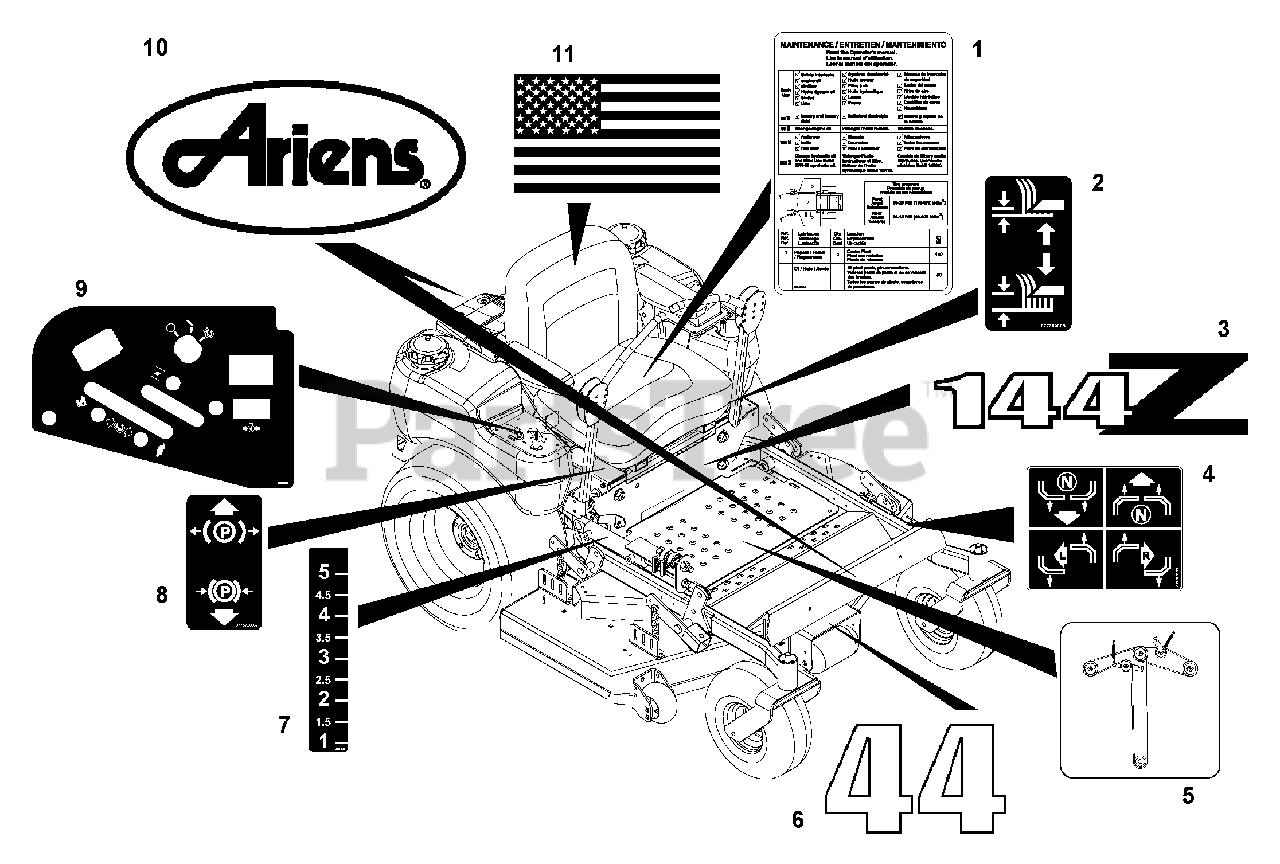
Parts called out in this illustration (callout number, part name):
1	DECAL, MAINTENANCE INSTRUCTION
2	DECAL- LIFT LEVER
3	DECAL, LOGO - GRAVELY 144Z
4	DECAL, INSTRUCTIONAL-STEERING
5	DECAL, GRAVELY BELT DIAGRAM
6	DECAL, 44"
7	DECAL, HEIGHT OF CUT
8	DECAL, PARKING BRAKE LEVER
9	DECAL CONTROL PANEL
10	DECAL, ARIENS
11	DECAL, AMERICAN FLAG
